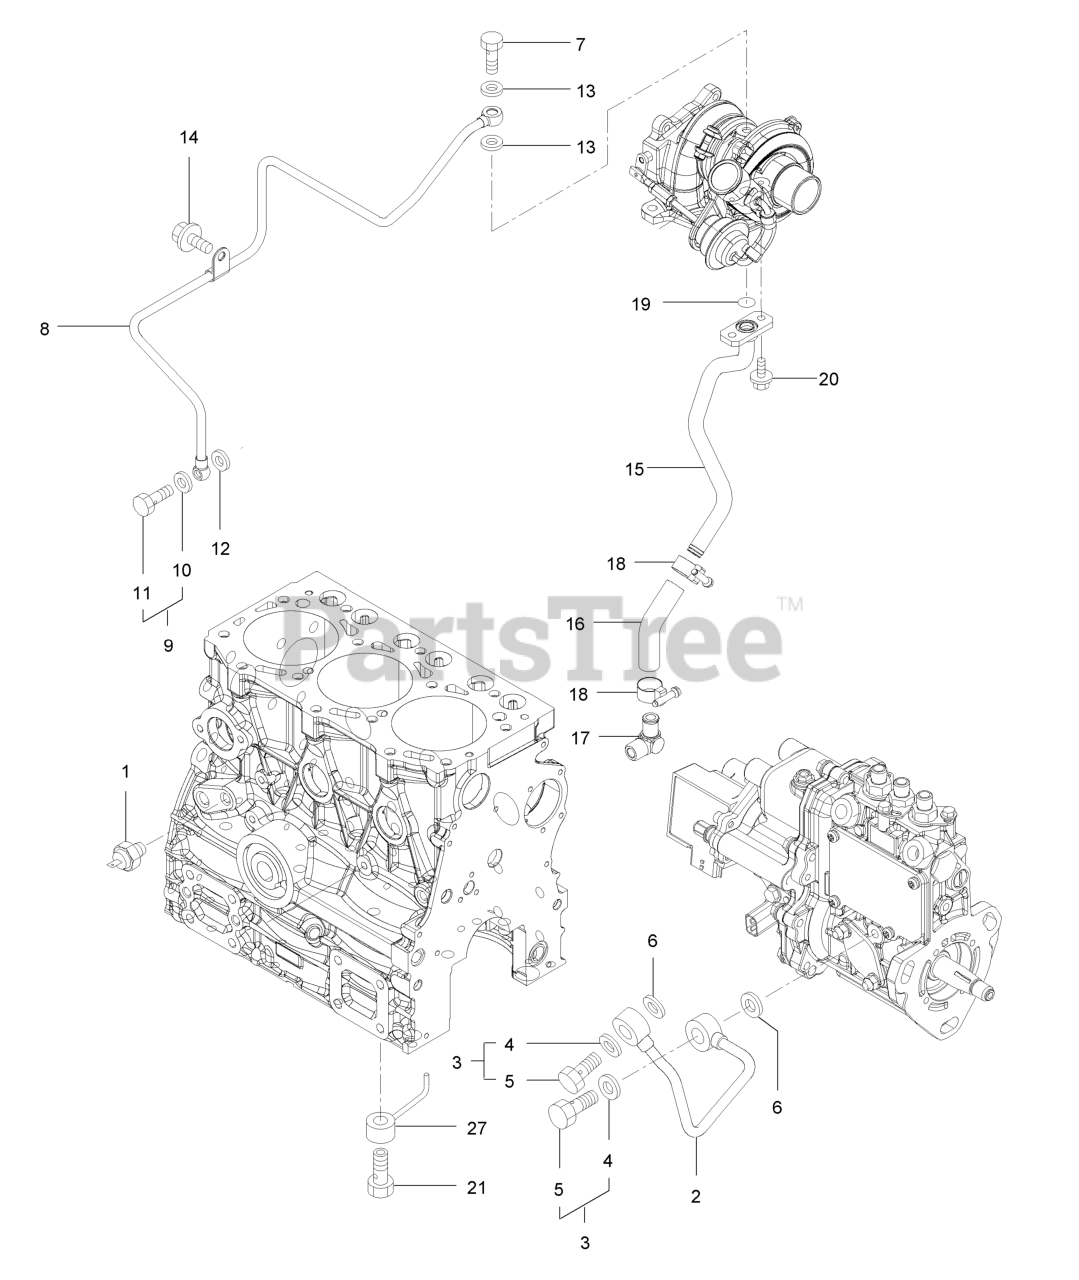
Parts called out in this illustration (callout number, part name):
1	Switch-Oil
2	Pipe-Oil
3	Joint Bolt ASM
4	Washer-Seal
5	Bolt-Joint
6	Washer-Seal
7	Bolt-Joint, Pipe
8	Pipe ASM-Lo
9	Joint Bolt ASM
10	Washer-Seal
11	Bolt-Joint
12	Washer-Seal
15	Pipe-Lo Return
18	Clamp-Hose
21	Valve ASM-Check
27	Nozzle ASM-Piston
